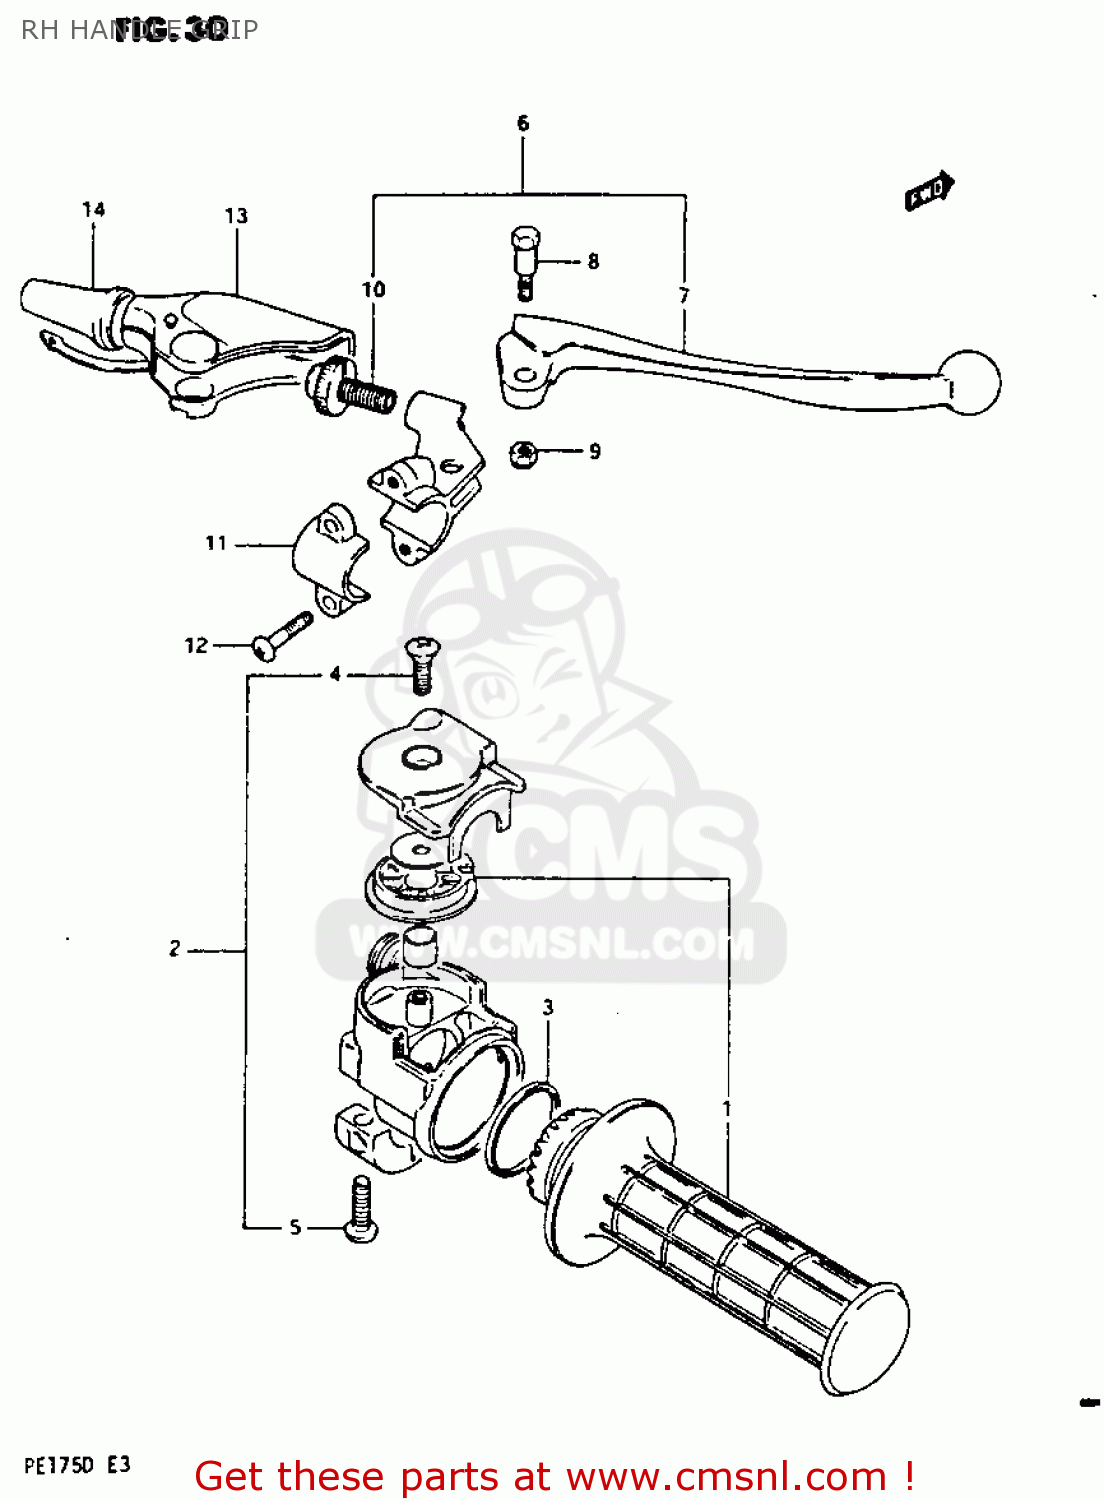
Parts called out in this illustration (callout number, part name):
1	GRIP SET,THROTTLE
2	CASE ASSY,THROTTLE
3	V-RING,THROTTLE GRIP
4	SCREW 5X16
5	SCREW 5X20
6	LEVER ASSEMBLY,BRAKE
7	LEVER,BRAKE
8	BOLT,LEVER PIVOT
9	NUT 6MM
10	ADJUSTER,CABLE
11	BRACKET,LEVER
12	SCREW
13	COVER,BRAKE LEVER
14	BOOT,CLUTCH CABLE
